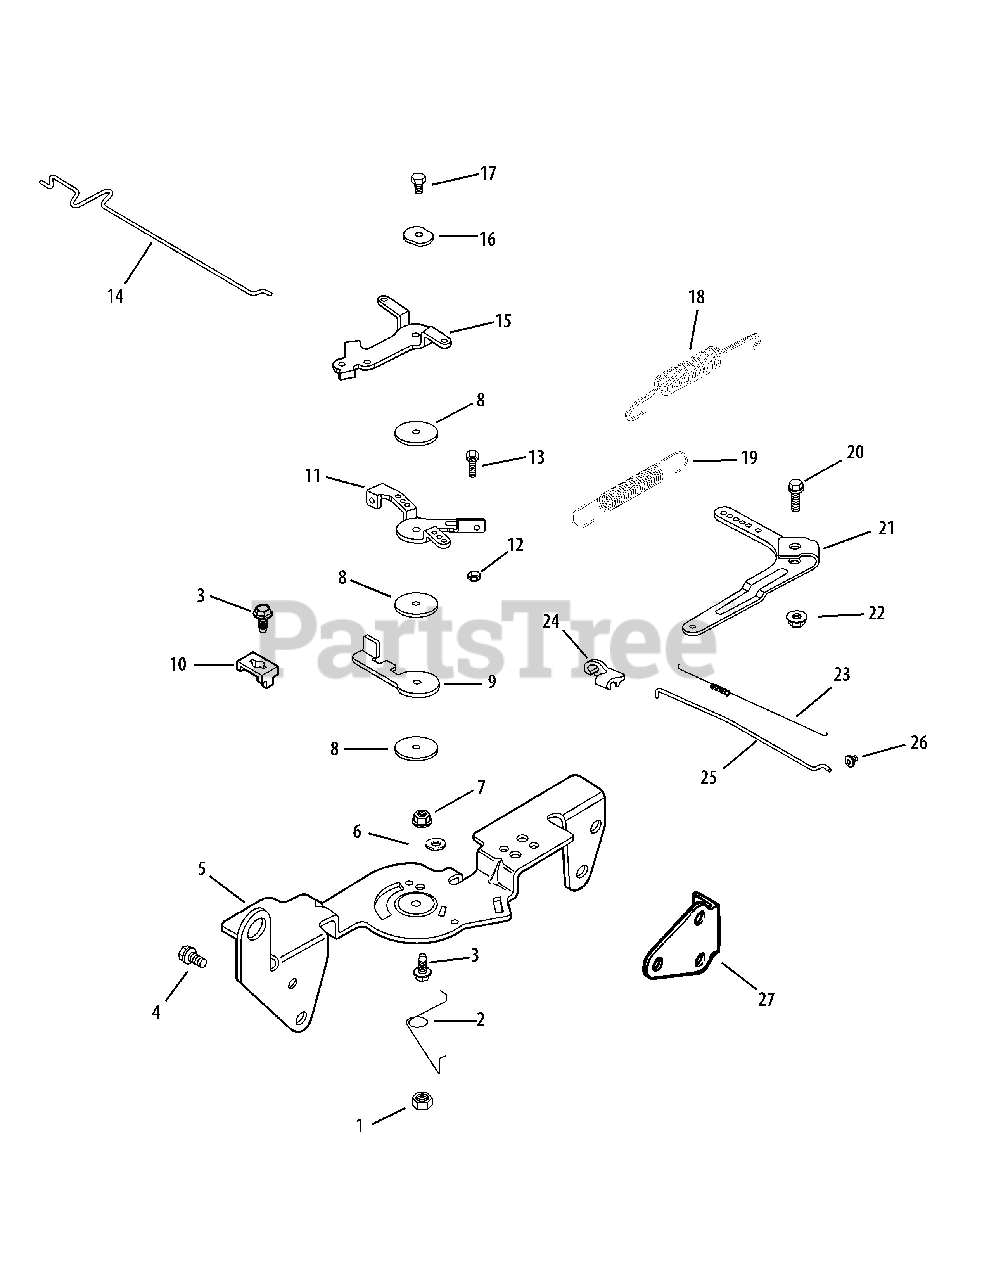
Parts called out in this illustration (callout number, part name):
1	Nut, Lock M5X.8
2	Spring, Choke Return
3	Screw, Flg Thd Frm M5X0.8X16
4	Screw, Flg Thd Frm M6x1.0x16
5	Bracket, Control
6	Washer, Spring Lock 1/4"
7	Nut, Flg M5x.8
8	Washer, Flat 5.5 MM
9	Lever Throttle Actuator
10	Clamp, Cable
11	Lever Throttle Control
13	Screw, Cap M4X0.7X30
14	Linkage, Choke
15	Lever, Choke
16	Washer, Spring 1/4"
17	Screw, Flg Thd Frm M5X0.8X20
18	Spring, Throttle Limiter
19	Spring, Governor
20	Bolt, Rd Hd Sq Neck M6X1.0X25
21	Lever, Governor
22	Nut, Flg M6x1.0
23	Spring, Linkage
24	Bushing, Linkage Retaining
25	Linkage, Throttle
26	Bushing, Throttle Linkage
